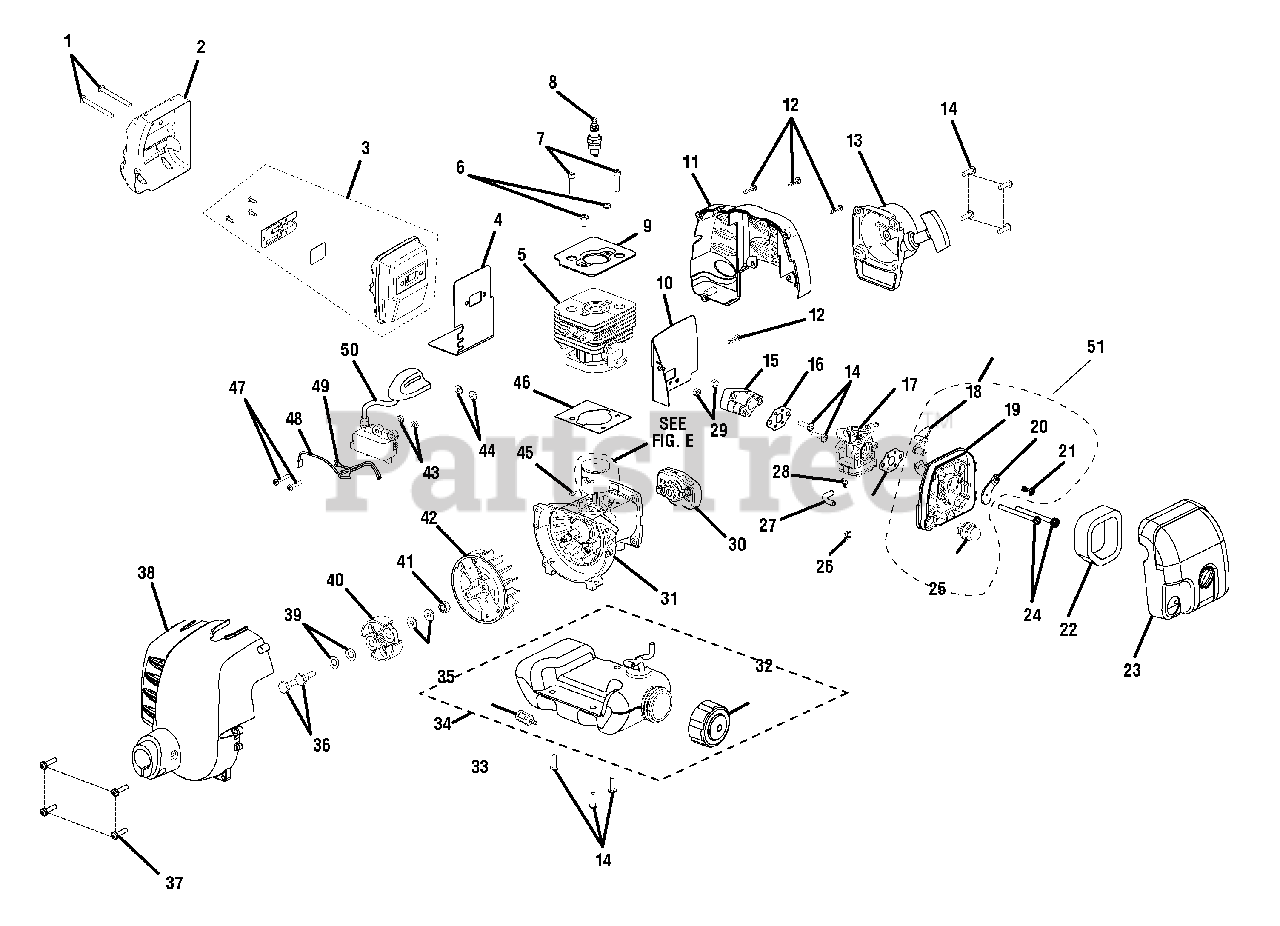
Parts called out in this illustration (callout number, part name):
1	SCREW (M5 X 50 mm TORX SLOTTED RECESSED PAN HD.)
2	HEAT SHIELD
3	MUFFLER ASSEMBLY
4	MUFFLER GASKET
5	CYLINDER
6	SCREW (M5 X 10 in. TORX RECESSED PAN HD.)
7	SCREW (M5 X 22 mm SOCKET HD.)
8	SPARK PLUG
9	CYLINDER PLATE
10	INSULATOR GASKET
11	ENGINE HOUSING, REAR
12	SCREW (M4 X 16 mm TORX RECESSED PAN HD.)
13	STARTER RECOIL ASSEMBLY
14	SCREW (M5 X 16 mm Torx SLOTTED RECESSED PAN HD.)
15	HEAT DAM INSULATOR
16	CARBURETOR GASKET
17	CARBURETOR ASSEMBLY
18	CHOKE LEVER
19	CARBURETOR PLATE
20	CHOKE PLATE
21	SCREW (M4 X 12 mm SLOTTED RECESSED PAN HD.)
23	COVER ASSEMBLY
24	SCREW (M5 X 60 mm, SLOTTED RECESSED PAN HD. MACHINE)
25	PRIMER ASSEMBLY
26	HOSE CLIP
27	FUEL LINE
28	HOSE CLIP
29	NUT (M5 x .8 mm)
30	PULLEY ASSEMBLY
31	CRANKCASE ASSEMBLY
32	FUEL CAP ASSEMBLY
33	FUEL FILTER
34	FUEL TANK ASSEMBLY
36	CLUTCH SCREW
37	SCREW (M5 X 20 mm TORX SLOTTED RECESSED PAN HD.)
38	FRONT HOUSING ASSEMBLY
39	CURVED WASHER
40	CLUTCH ASSEMBLY
41	ROTOR NUT
43	IGNITION COIL SPACER
44	WASHER (3/16 x 3/64)
45	WOODRUFF KEY (10 mm X 3 mm)
47	SCREW (M4 X 22 mm TORX SLOTTED RECESSED PAN HD.)
48	LEAD ASSEMBLY, BLACK
49	LEAD ASSEMBLY, RED
50	COIL BOOT ASSEMBLY
51	FILTER HOUSING ASSEMBLY
